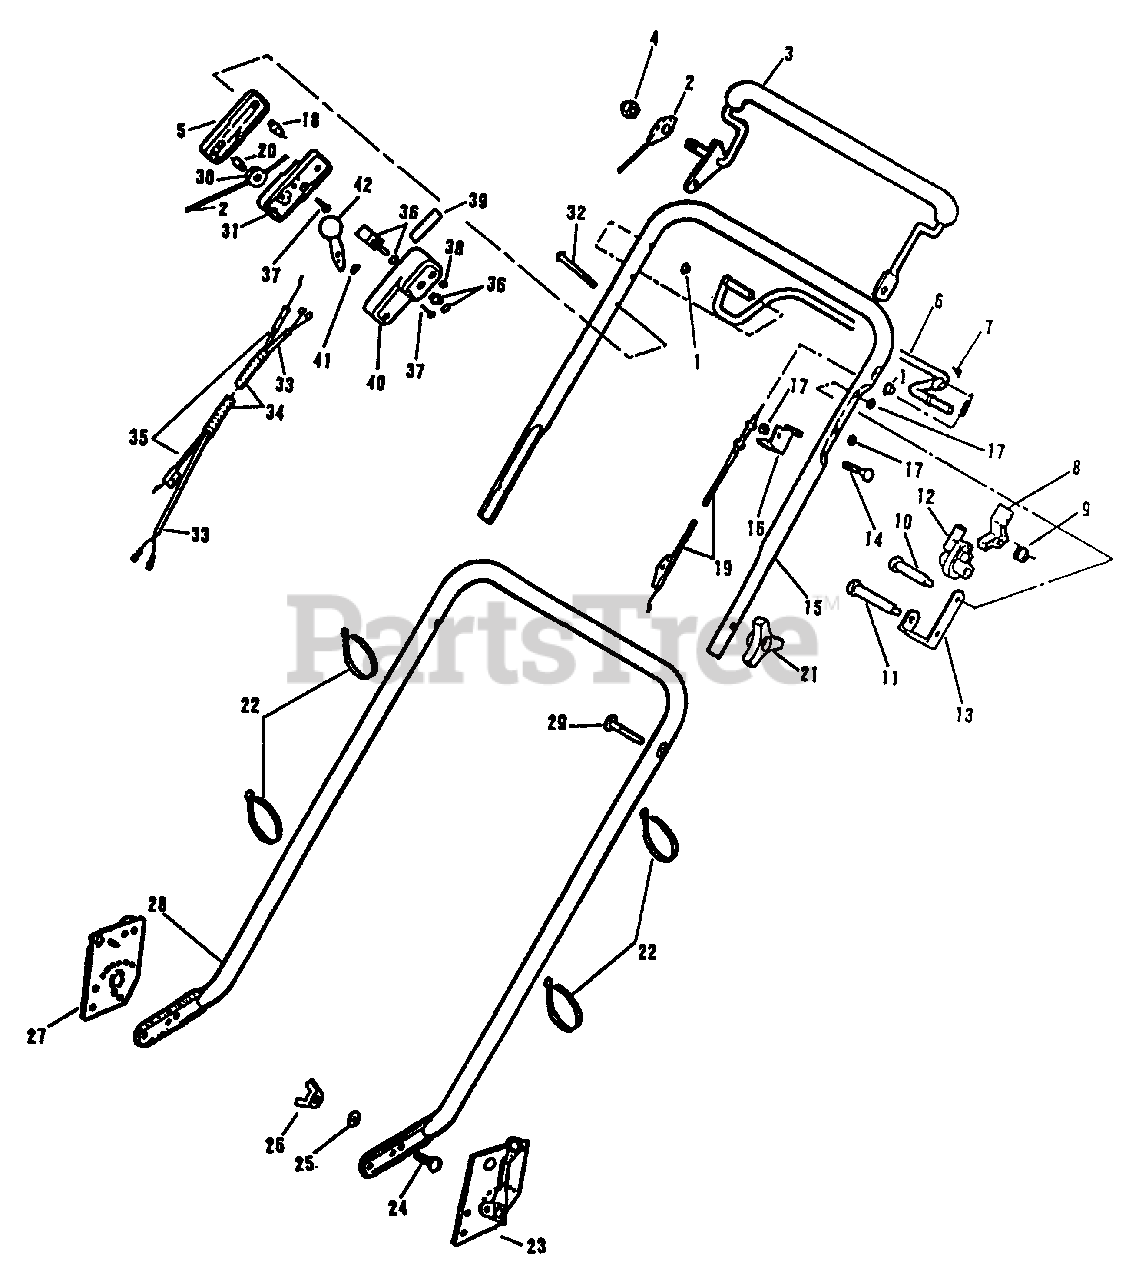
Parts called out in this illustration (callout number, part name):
1	Palnut
2	Control Cable Assembly
3	Control Lever Assembly
4	Acorn Nut
5	Control Case-Outer
6	Control Lever-Bail
7	Palnut
8	Stop-Latch Lever
9	Spring-Torsion
10	Bolt, Shoulder
11	Bolt, Shoudler
12	Cam
13	Bracket
14	Screw
15	Handle Section-Top
16	Conduit Anchor
17	Nut
18	Column
19	Control Cable Assembly
20	Pin-Pulley
21	Handle Knob
22	Tie Strap
23	Handle Bracket-L.H.
24	Bolt
25	Washer
26	Wing Nut
27	Handle Bracket-R.H.
28	Handle Section-Lower
29	Screw
30	Pulley
31	Throttle Case-Center
32	Screw
33	Wire Harness Assembly
34	Spiral Tubing
35	Throttle Cable
36	Switch Assembly
37	Screw
38	Nut
39	Decal-Throttle Control
40	Throttle Case-Inner
41	Washer
42	Lever and Knob Assembly
